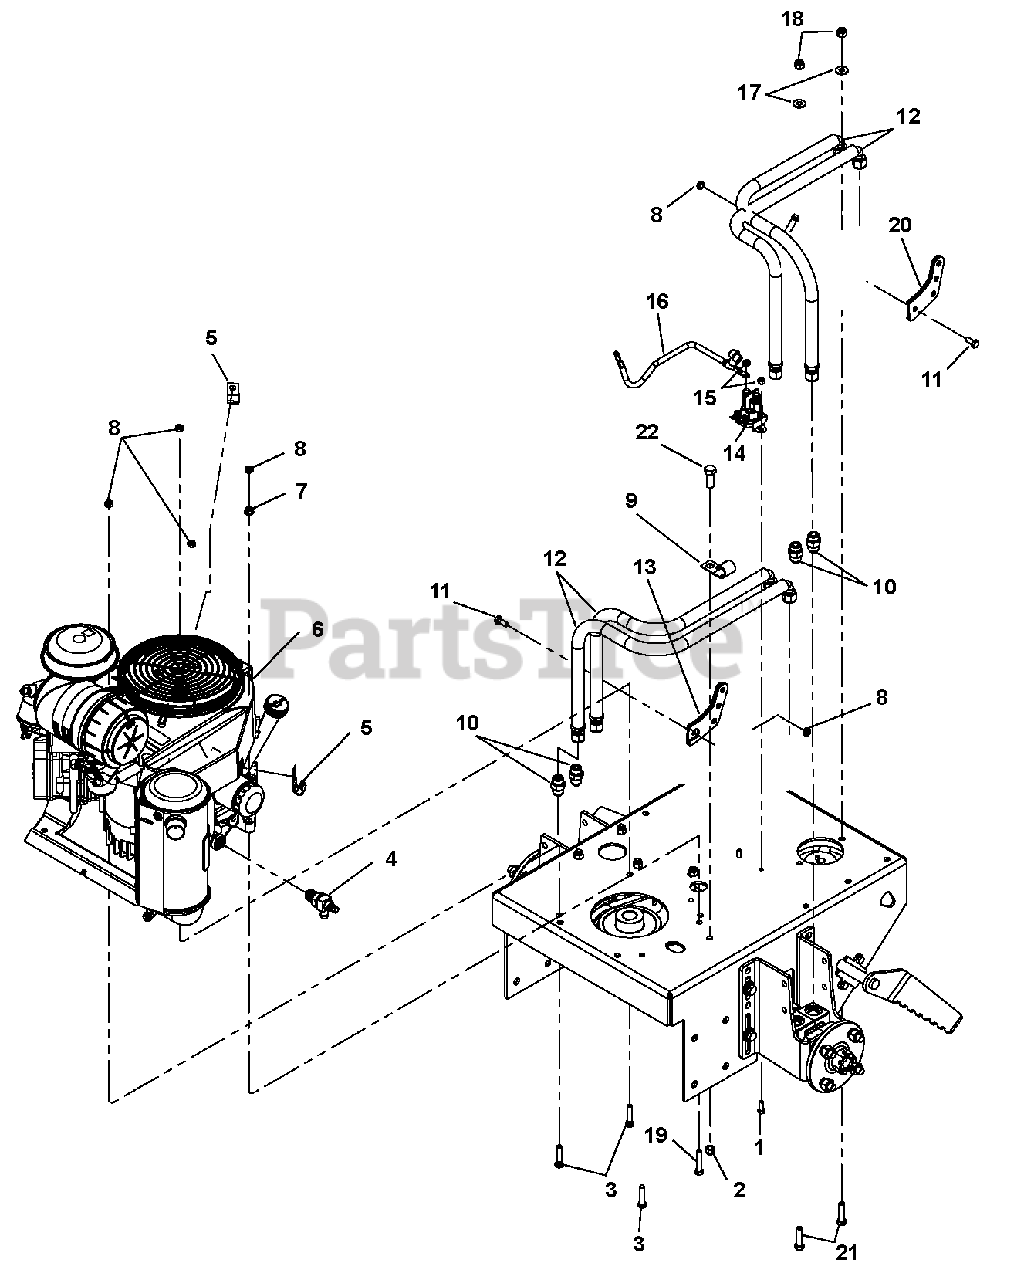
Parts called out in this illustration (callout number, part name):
1	Bolt, Hex .25-20 x .75 Grade 5 (988141, 142)
2	Locknut, .38-16 Nyloc (988140)
3	Bolt, .31-18 x 1.50 Hex Grade 5
4	Fitting, Oil Drain
5	Pillow-Clip, .500 Insulated
6	Engine, Kawasaki 19HP FH580V (988141, 142)
7	Locknut, 5/16-18 WHIZ
8	Locknut, 5/16-18 Nyloc
9	Pillow-Clip, .500 Insulated (988140)
10	Fitting, Straight
11	Bolt, 5/16-18 x .750 Hex Grade 5
12	Hose, Hydraulic .50 x 26.50 EZFLEx
13	Weldment, CSWS Hydro Pump Arm
14	Solenoid, 12V Starter (988141, 142)
15	Locknut, .25-20 Nyloc (988141, 142)
16	Cable, 12" Starter (988141, 142)
17	Washer, .313 Regular Flat
18	Locknut, .38-16 Nyloc
19	Bolt, .31-18 x 1.75 Hex Grade 5
20	Weldment, CSWS Left Hand Hydro Pump Arm
21	Bolt, .38-16 x 1.50 Hex Grade 5
22	Bolt, .38-16 x 1.00 Hex Grade 5
